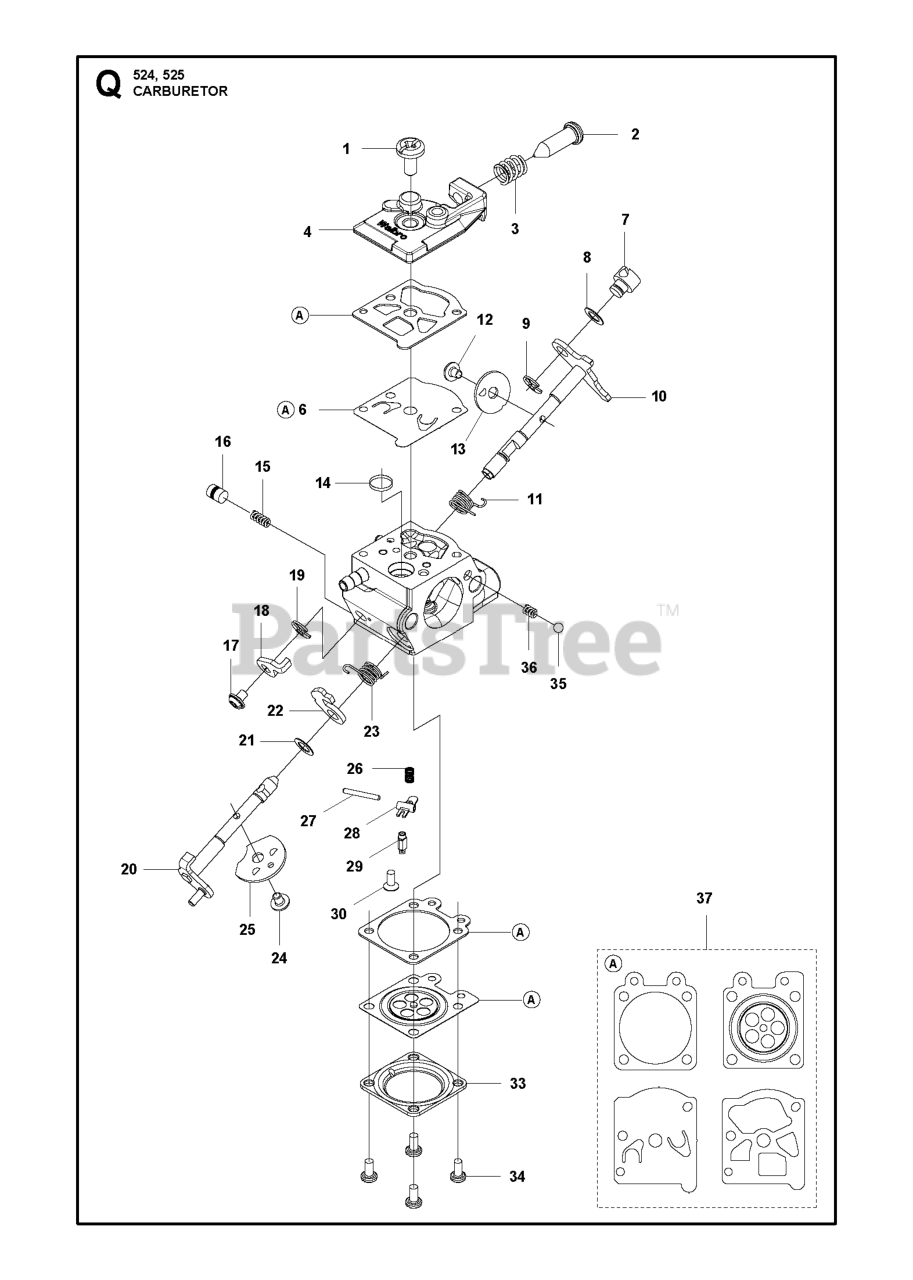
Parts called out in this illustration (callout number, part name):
2	SCREW, IDLE
4	COVER PUMP
6	PUMP DIAPHRAGM
9	RING
10	SHAFT ASSEMBLY,THROTTLE
14	SCREEN
16	PISTON ASSY
18	LEVER THROTTLE
20	SHAFT ASSEMBLY,CHOKE
29	VALVE INLET
34	SCREW ASSY
36	CHOKE SPRING
37	GASKET KIT
